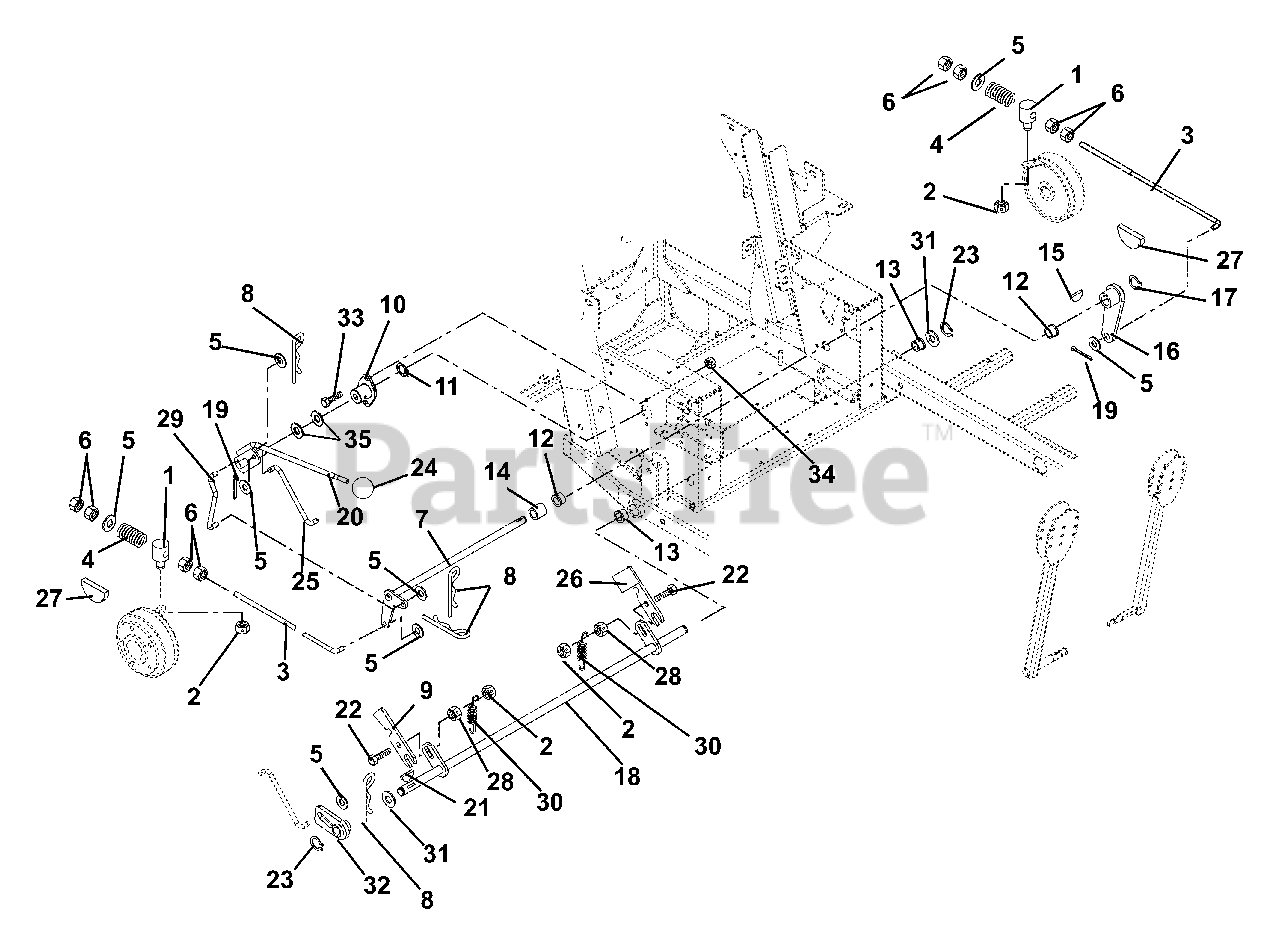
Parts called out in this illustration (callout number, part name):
1	Pivot, Brake Rod
2	Nut, Locking Center .31-18
3	PTO Link Rod
4	Spring, Compression .143 x .710 x 2.00
5	Washer, Flat Steel .406 x .812 x .065
6	Nut, Hex .38-16
7	Shaft, Brake Cross
8	Pin, Hair
9	Slide, Interlocking Brake
10	Bushing, Flange
11	Ring, Retaining External .625 x .05
12	Bushing, Flange Nylon .762 x 1.00 x .58 x 1.48
13	Bushing, Flange .515 x .75 x .745 x 1.00
14	Bushing, Sleeve .75 x 1.00 x .75
15	Key, Woodruff .19 x .75 Hard #9
16	Arm, Brake
17	Ring, Retaining External .69 x .077
18	Weldment, Mechanical Brake
19	Pin, Cotter External .09 x .75
20	Weldment, Brake Actuating
21	Key, Woodruff .13 x .63
22	Bolt, Hex .31-18 x 1.25 Grade 5
23	Ring, Retaining External .50 x .05
24	Knob, Steering Lock
25	Linkage, Brake Actuating
26	Interlock, Safety Switch
27	Pad, Disk Brake
28	Nut, Locking Top Flange .31-18
29	Linkage, Brake Actuating
30	Spring, Tension .048 x .44 x 1.75
31	Washer, Flat Steel .505 x 1.00 x .062
32	Weldment, Parking Brake Hub
33	Bolt, Hex .31-18 x .75 Grade 5
34	Nut, Locking Top Flange .31-18
35	Washer, Flat Steel .630 x 1.25 x .062
